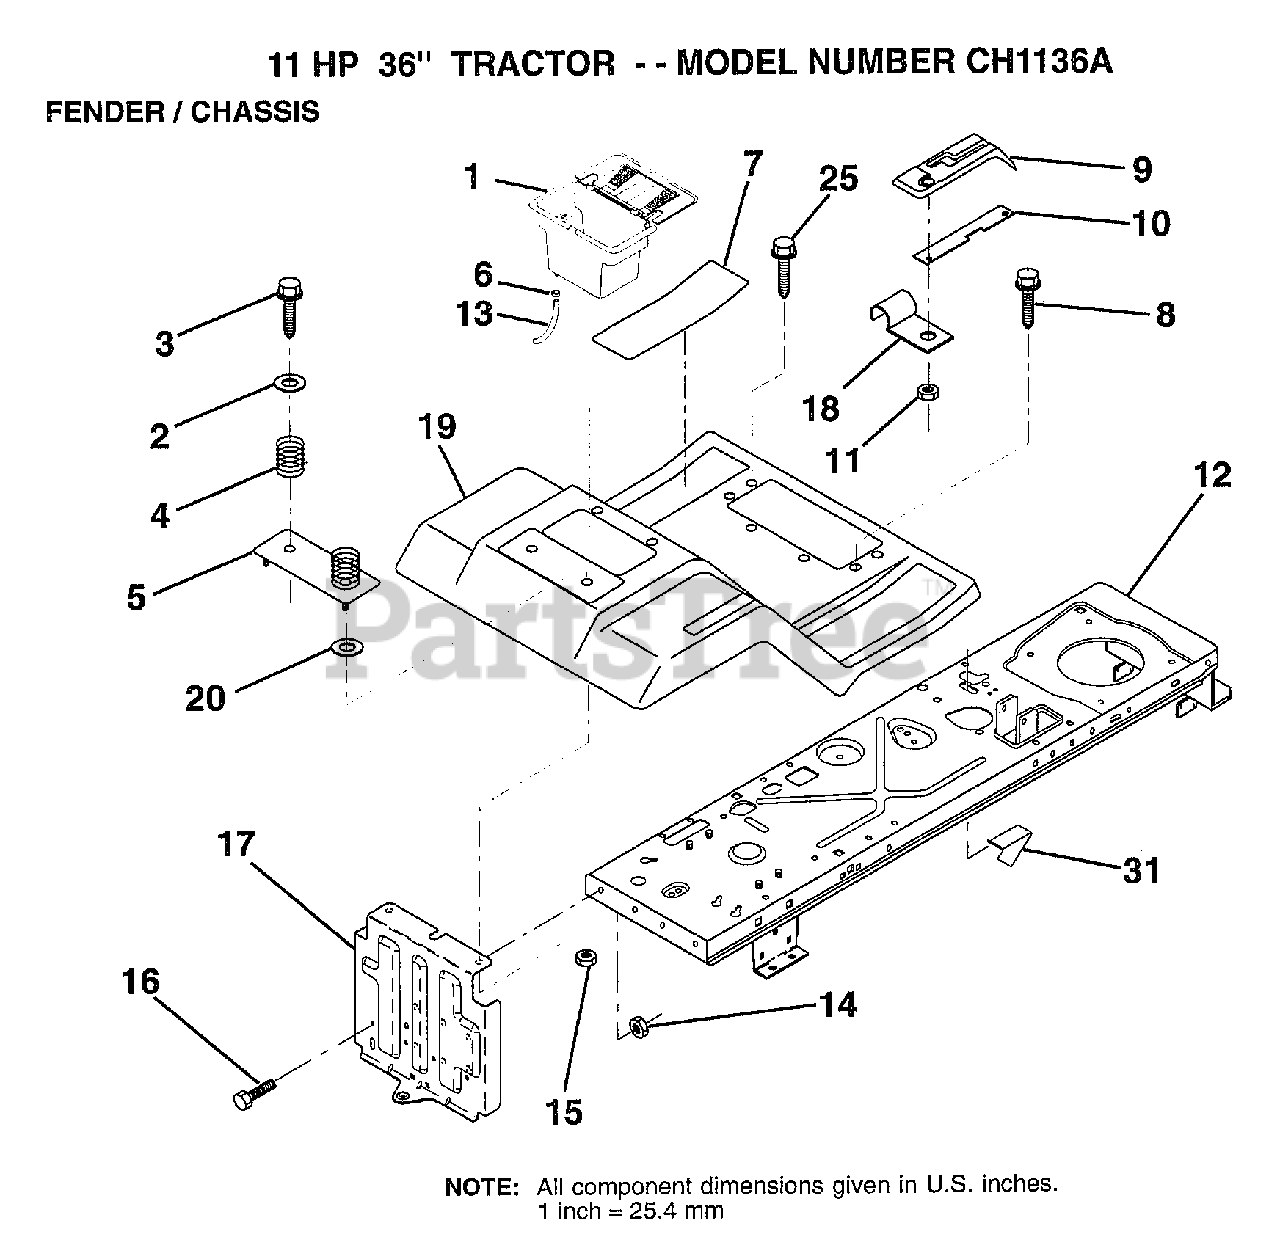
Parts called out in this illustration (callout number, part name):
2	WASHER
3	SCREW
4	SPRING COMPRESSIO
5	BTRY FENDER PLATE
6	HOSE CLAMP T
7	PAD FOOTREST
8	SCREW
9	CONSOLE SHFT 4SP
10	PLATE LOCK SHIFT
11	NUT
13	TUBE T
14	NUT
15	NUT
16	BOLT
17	DRAWBAR ASM LR
18	"CLIP,INSULATOR"
19	FENDER/FOOT MS505
25	SCREW TI
